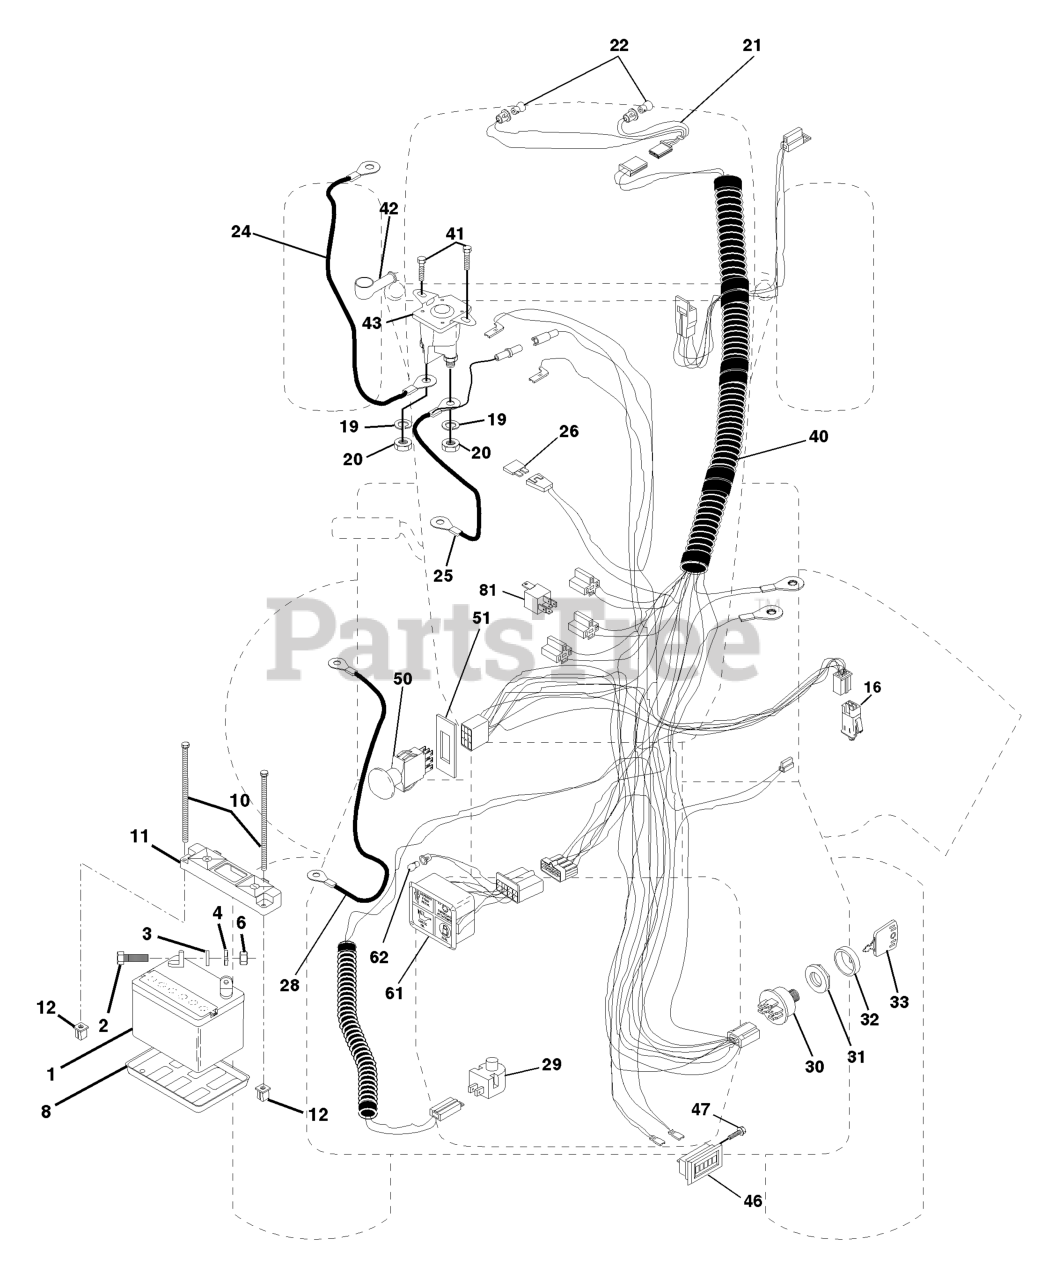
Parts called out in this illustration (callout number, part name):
1	BATTERY 12V .35 AMP
2	BOLT.HEX.1/4.X.3/4.DICHROMATE
3	LOCKWASHER
4	WASHER
6	NUT
8	BATTERY TRAY T
10	BOLT 1/4-20 X 7.5
11	BATTERY HOLDDOWN FRONT MOUNT
12	NUT, PUSH NYLON 1/4" BATTERY
16	SWITCH INTERLOCK
19	LOCKWASHER
20	NUT
21	HARNESS LIGHT SOCKET
24	CABLE, STARTER
25	CABLE, BATTERY
28	CABLE, GROUND
29	PLUNGER SWITCH (COLOR:OLIVE)
30	SWITCH.IGNITION.4.POSITION
31	NUT IGNITION
32	COVER SWITCH KEY
33	KEY.MOLDED.GENERIC
40	HARNESS.IGNITION
41	SCREW
42	TERMINAL COVER
43	SOLINOID
46	HOUR METER T
47	Screw #10-24 x 1/2
50	SWITCH PTO 3 PDT
51	FRAME RETAINING RING
61	LIGHT PACKAGE
62	BULB LIGHT T
81	RELAY.ASSY.T
